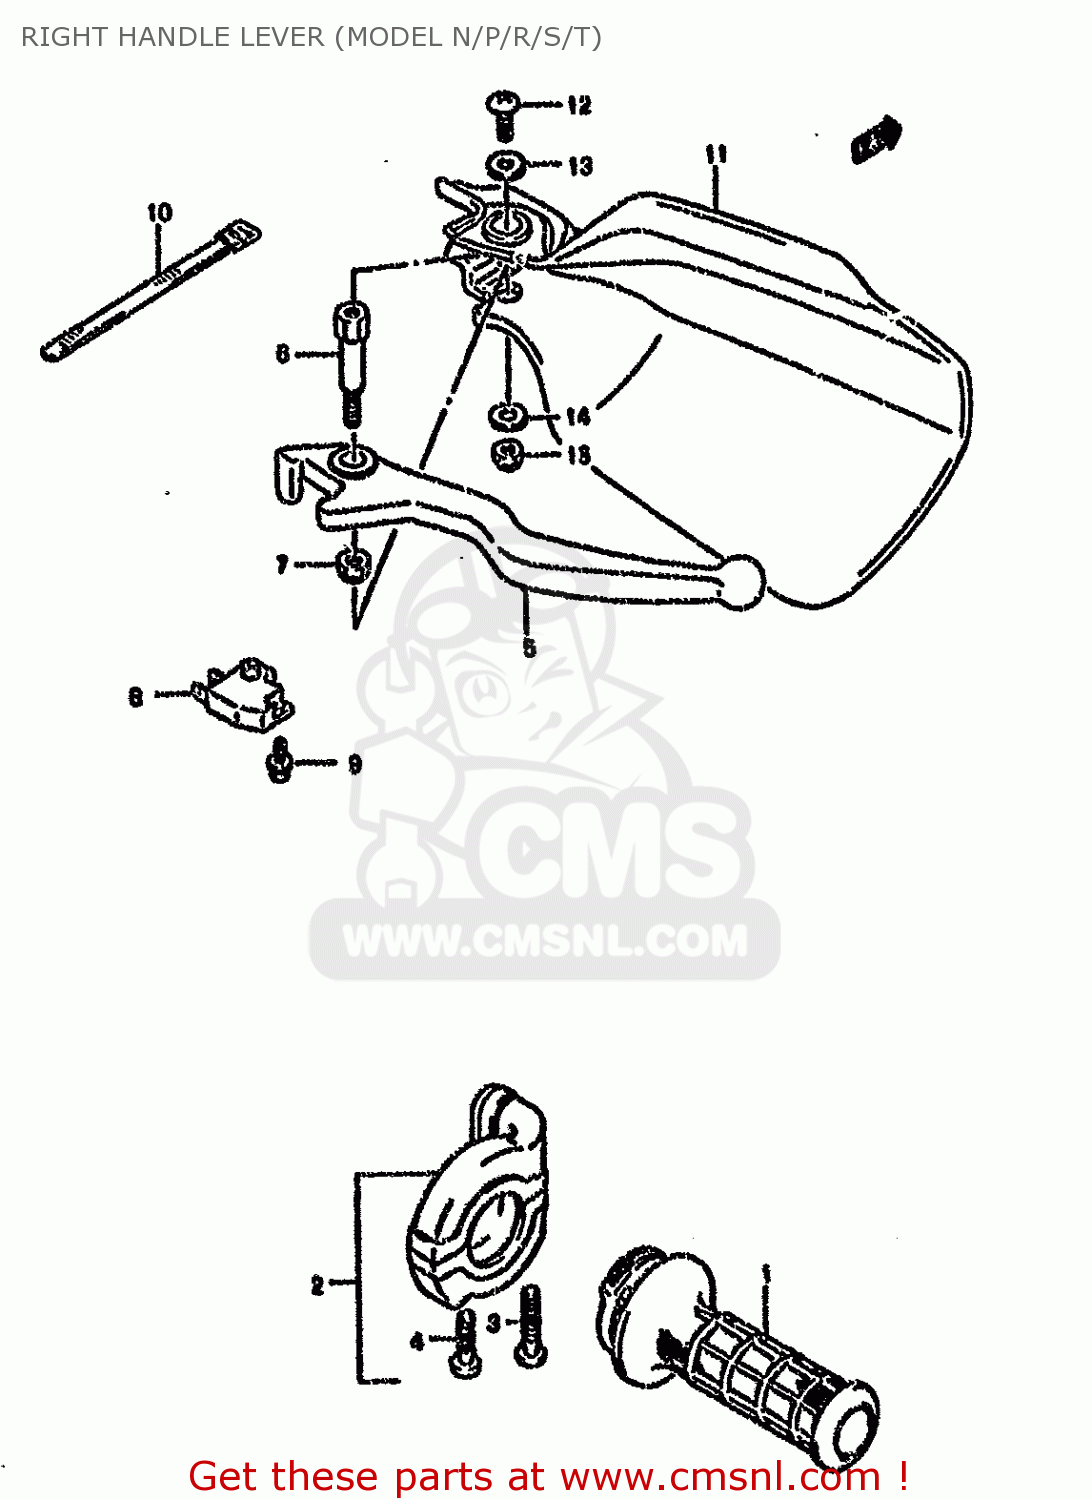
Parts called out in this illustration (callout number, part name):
1	GRIP,THROTTLE
2	CASE ASSY,THROTTLE
3	SCREW(5X25)
4	SCREW 5X20
5	LEVER,BRAKE
6	BOLT,BRAKE LEVER PIVOT
7	NUT
8	SWITCH ASSEMBLY,STOP
9	SCREW
10	CLAMP(L:120)
11	COVER,KNUCKLE,R
12	SCREW
13	WASHER (5.5X16X1.2)
14	WASHER (6.5X17X1.6)
15	NUT 6MM
